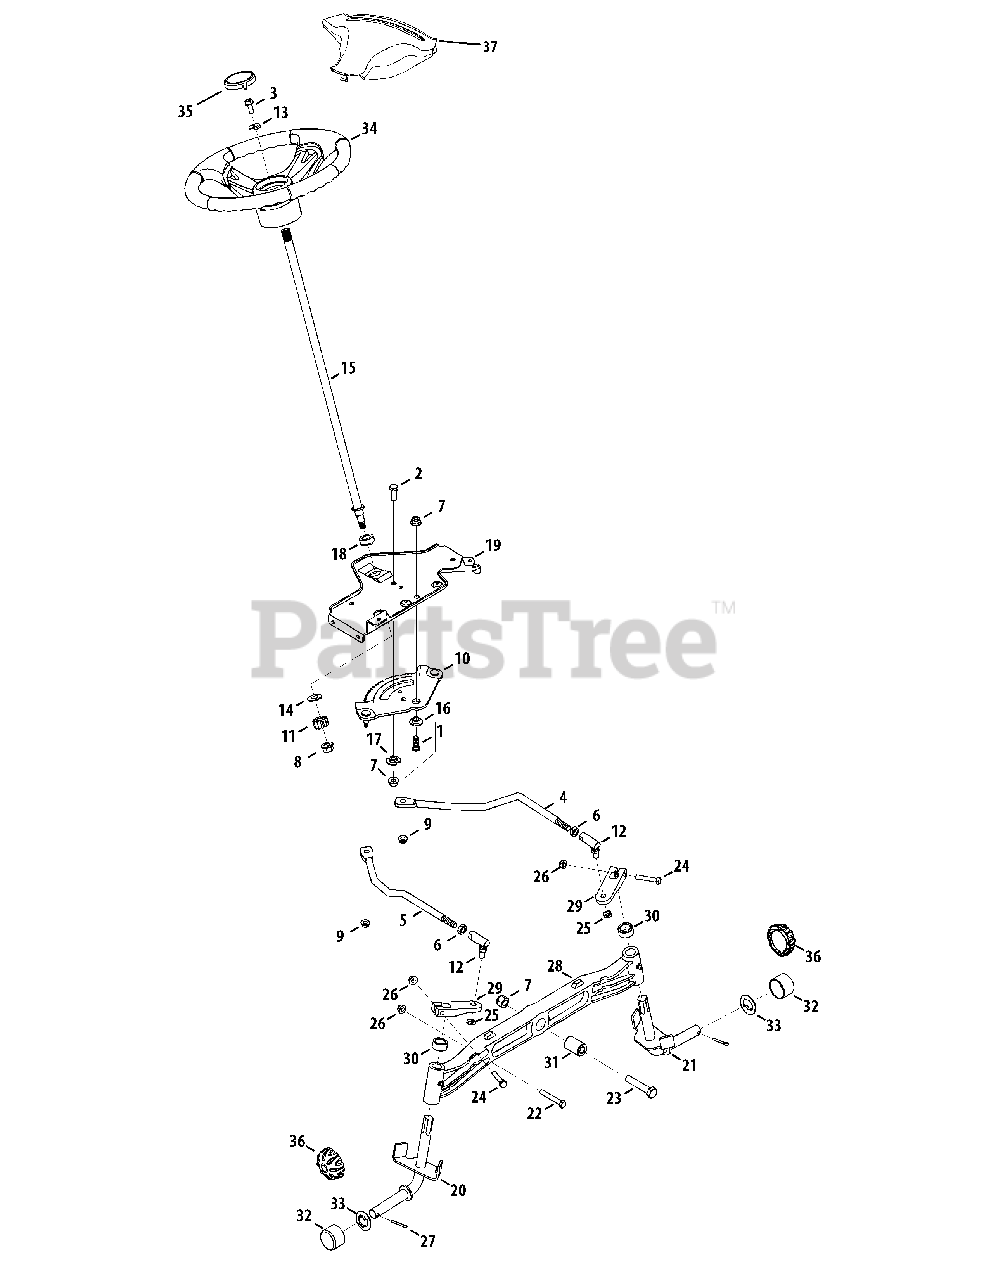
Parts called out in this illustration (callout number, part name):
1	Screw, 3/8-16 x 1.0
2	Hex Screw 3/16 x 1.00
3	Hex Screw 5/16-18 x 1.00 Special
4	Link, Drag LH
5	Link, Drag RH
6	Hex Jam Nut 7/16-20
7	Flange Lock-Nut 3/8-16 Gr. F Nylon
8	Flange Lock Nut, 7/16-20
9	Hex Flange L-Nut 5/16-18
10	Steering Gear, 11/90 Ratio
11	Steering Pinion Gear
12	Ball Joint, 7/16 - 20
13	Flat Washer .406 ID x .875 DE x .105
14	Fl. Washer .510 x 1.120 x .060
15	Steering Shaft .625 OD x 24.25
15	Steering Shaft .625 OD x 25.00
16	Shoulder Spacer .385 x 1.25 x .3025
17	Spacer .38x 1.375 Special
18	Hex Flange Bearing 5/8
22	Hex Bolt 5/16-18 x 2.25
23	Hex Cap Screw, 3/8-16 x 2.5
24	Hex Screw 5/16-18 x 1.75" Lg.
25	Hex Cent L-Nut 3/8-24
26	Flange Locknut 5/16-18 Gr. F, Nylon
27	Cotter Pin 5/32" Dia.
28	Pivot Bar (cast)
29	Steering Block
30	Spacer .710 ID x .125 OD x .56
31	Spacer .385 x 1.0 x 1.5075
33	Flat Washer .350 x 1.559 x .062
34	Steering Wheel, Standard Grip
34	Steering Wheel, Softgrip
35	Steering Wheel Cap (spig) logo
35	Steering Wheel Cap (w/o spig) logo
36	Hub Cap
37	Steering Wheel Cover (w/sprigs)
